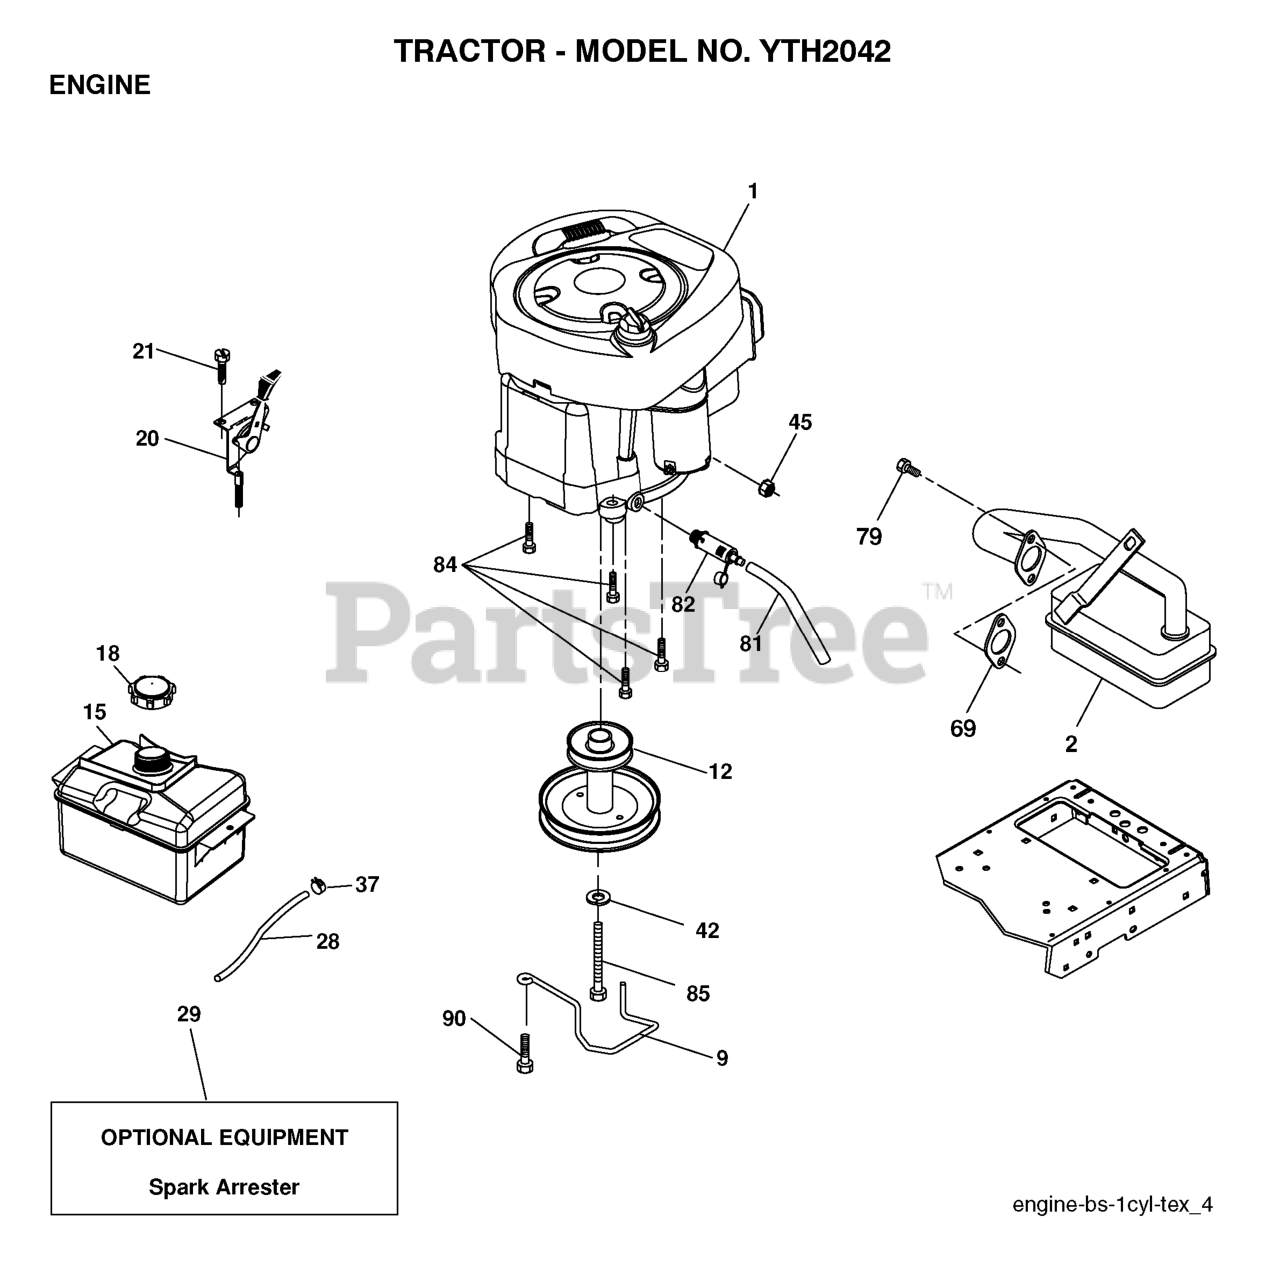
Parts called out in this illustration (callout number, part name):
2	MUFFLER.LT.BRIGGS.14HP.IC/OHV
9	KEEPER.BELT.ENGINE.4.2
12	PULLY ENGINE
15	TANK.ASM.FUEL.FR.2.5GA.
18	FUEL CAP
20	CONTROL.TH/CK.COBRA.KO
21	SCREW
28	LINE.FUEL.20"FRONT.EMI
29	KIT.SPARK ARRESTOR 794945 B&S
37	HOSE CLAMP
42	LOCKWASHER
45	NUT
69	REPL BY 532 27 22-93
79	SCREW.SOCKET HD.5/16-1
81	TUBE, DRAIN OIL ASM.
82	PLUG DRAIN OIL EASY
84	SCREW.3/8-16
85	BOLT HEX 7/16-20X4-1/4"
90	SCREW 3/8-16X1
